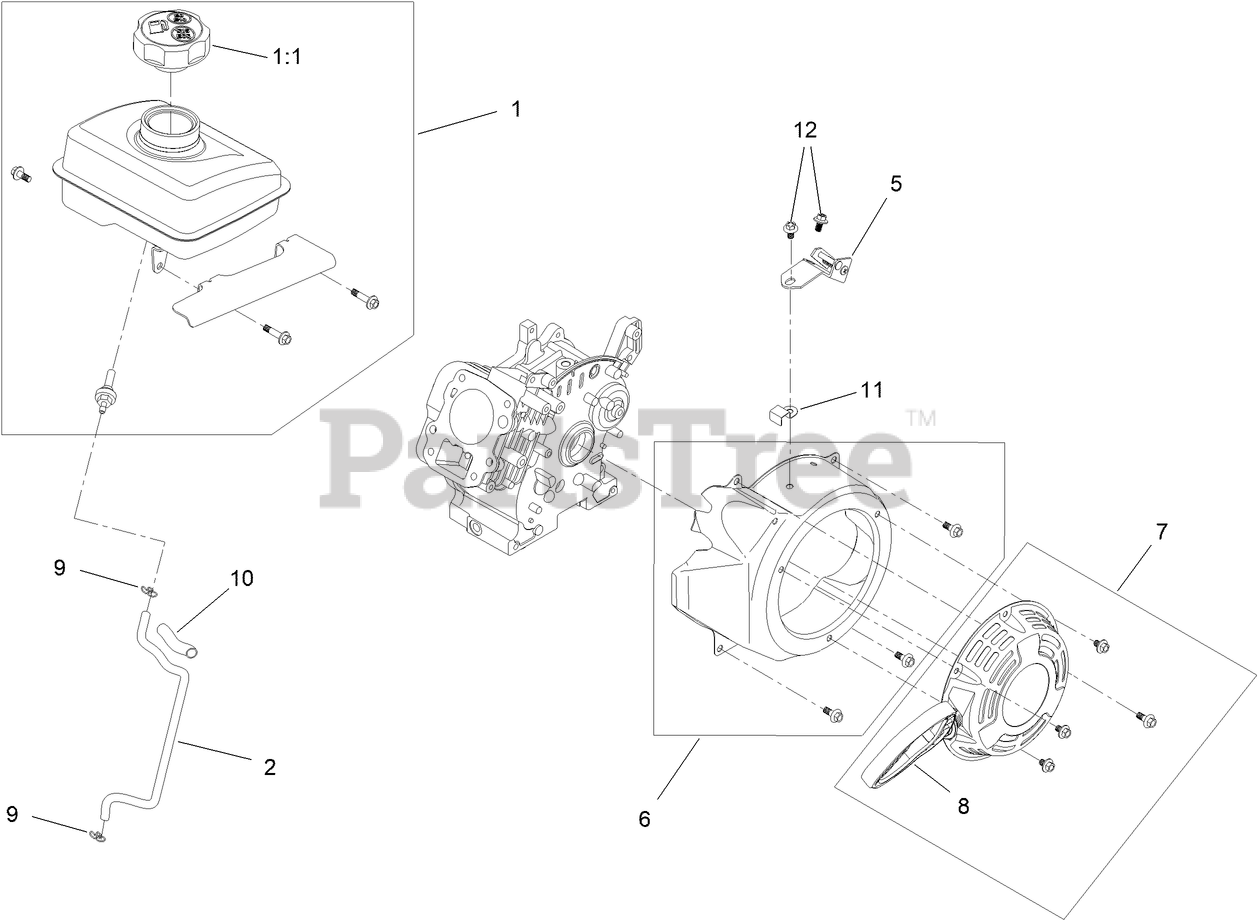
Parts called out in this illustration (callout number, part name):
1	FUEL TANK AND CAP KIT
1:1	CAP-FUEL
2	HOSE-FUEL
5	SPEED CONTROL ASM
6	BLOWER SHROUD KIT
7	RECOIL ASM KIT
8	HANDLE-RECOIL
9	CLIP-HOSE
10	SLEEVE-ABRASION
11	CLAMP-HOSE
12	SCREW-HHF
